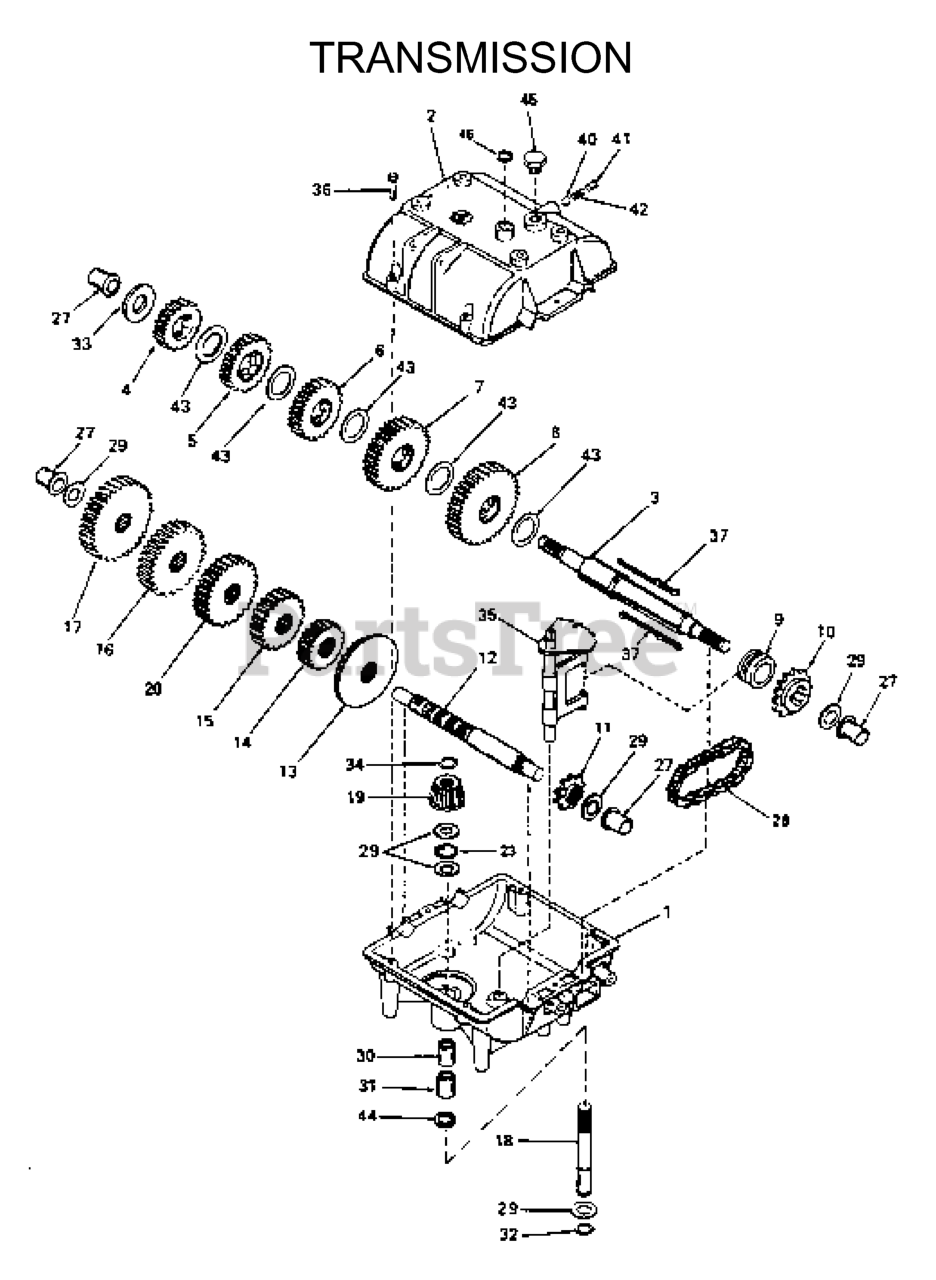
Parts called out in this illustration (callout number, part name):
1	DECAL, SHIFTER
2	SHIFTER PLATE
4	SB 12C X 34
5	ZERK
8	SHIFTER ARM
9	SHIFTER GRIP
10	SHIFTER BRACKET
11	SWITCH, TRANS
12	TRANSMISSION WB
13	REAR DECK W/DECALS
15	LOWER BELT SHIELD
16	KEY, #9 WOODRUFF
17	DRIVE SHAFT
19	RETAINER RING
20	PULLEY, DRIVE (36 & 48)
21	BELT, DRIVE (36 & 48)
22	SETSCREW, 1/4-20 NYLOC
23	PULLEY, INPUT
24	WASHER 1/2 FLAT
25	IDLER PULLEY
26	BELT, TRANSMISSION
27	BELT GUIDE
29	BUSHING, 10GA MACHINERY
30	SQUARE KEY - 1/4 X .5
33	KEY 1/4 SQ X 1 1/8
34	PULLEY, ENGINE
35	SPINDLE WASHER
36	WASHER 7/16 LOCK
37	HCS M10-1.5X35MM
38	HTB M8-1.125 X 25MM
39	WASHER.LOCK.HVY.HLCL.SPR.5/16
40	WASHER 5/16 FLAT
41	NUT 1/4C CENTER LOCK
42	HCS 1/4C X 1
44	SLW 3/8 STD
45	WASHER 1/4 FLAT
46	SET SCREW 5/16 NYLOC
47	RHSNB 3/8C X 2
48	NUT 3/8C CENTERBLOCK
49	HCS 5/16C X 3/4
50	NUT 5/16C CENTERLOCK
51	HCS 1/4C X 5/8
53	WASHER 3/8 FLAT
54	HAIRPIN #4
55	DECAL, DANGER
56	BLADE ROD 48"
57	DECAL, EXHAUST
58	DECAL, CLUTCH
60	BELT GUIDE - LONG
61	BELT GUIDE, SHORT
539100141	HCS 7/16F X 1 1/2
539100567	HCS M8-1.25 X 30MM
539102048	BLADE ROD 36"
539102149	DRIVE BELT (32)
539102154	DRIVE PULLEY (32)
